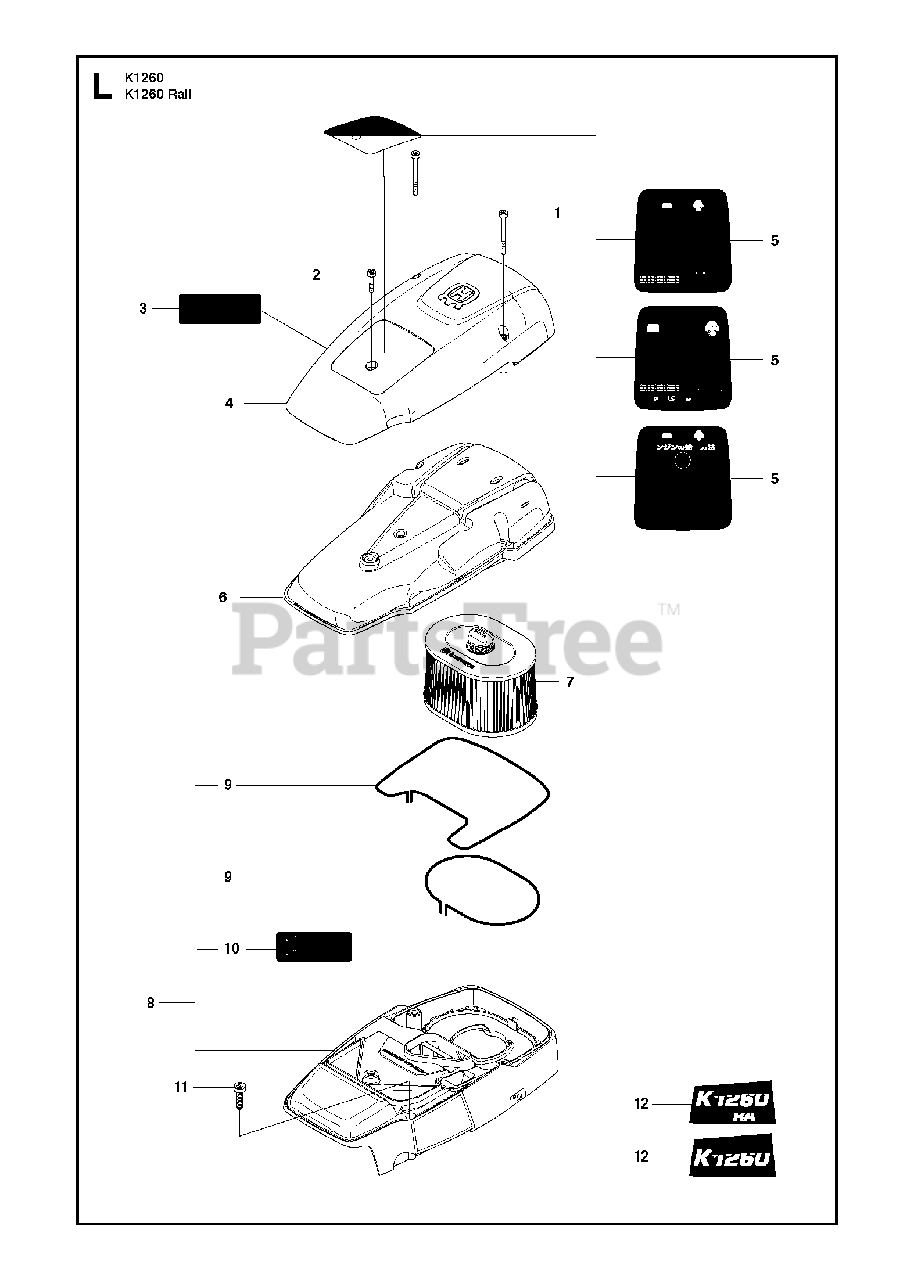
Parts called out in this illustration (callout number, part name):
1	SCREW ITXSCM
2	SCREW ITXSCM
5	DECALUSA
5	DECALCanada, CE
6	FILTER COVER
7	AIR FILTER
8	CYLINDER COVERIncl. 9 - 10
11	SCREW ITXSCM
12	LABELK1260 Rail
